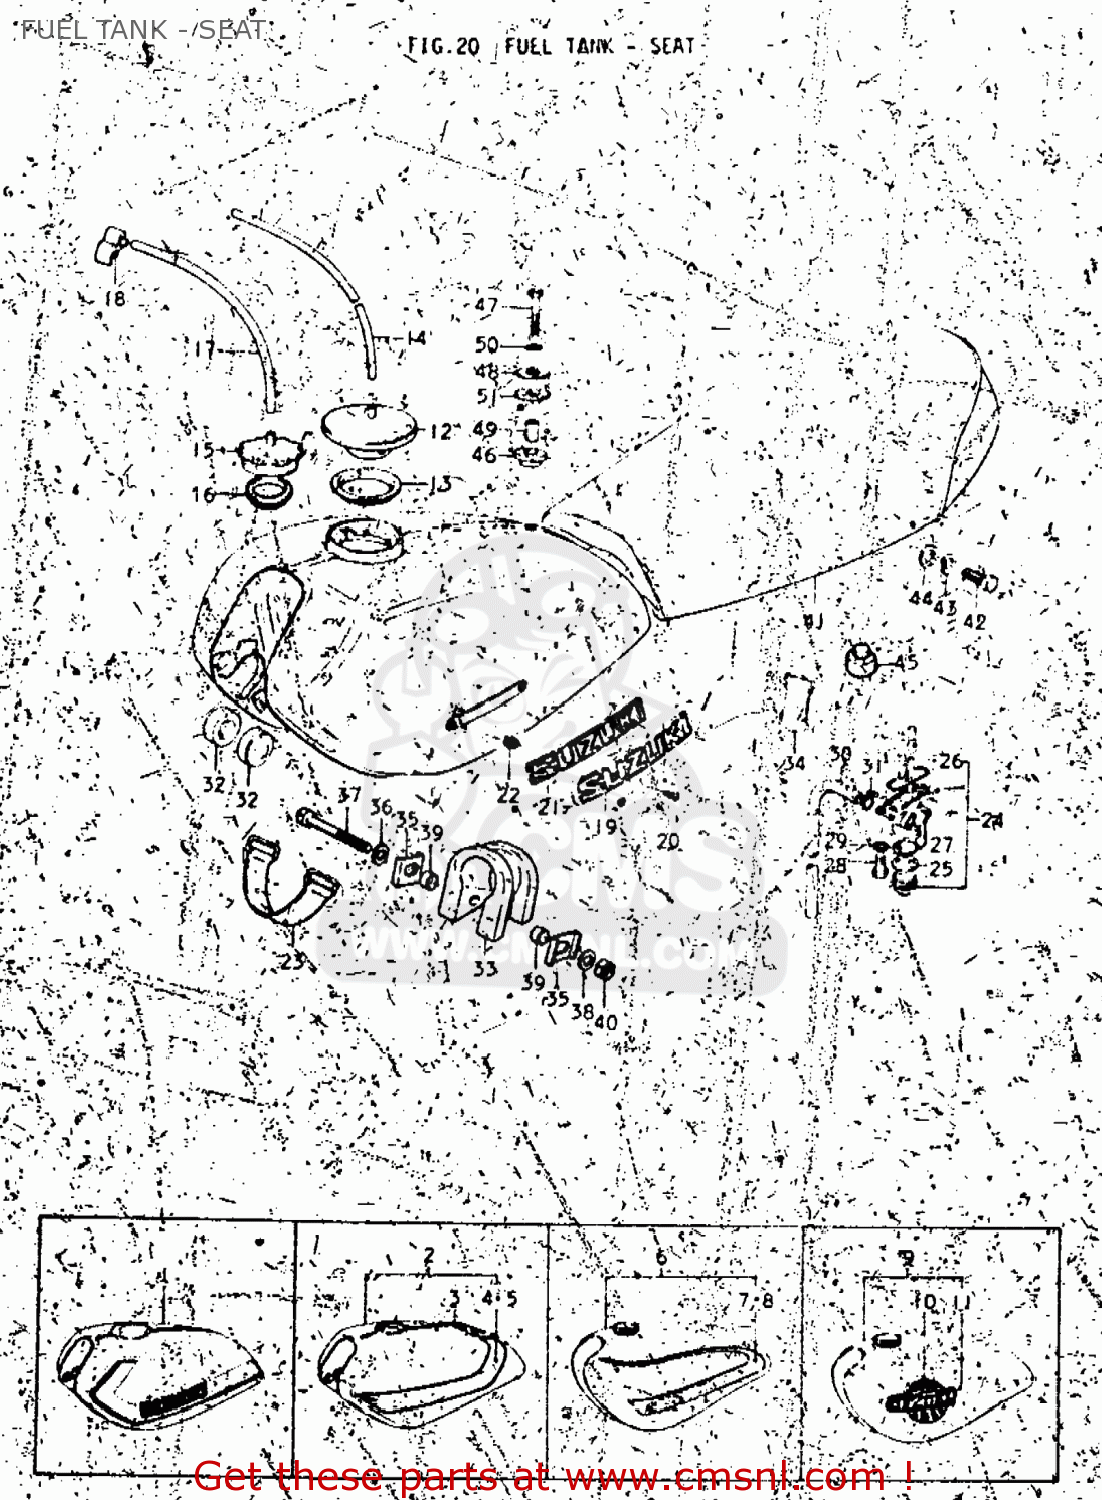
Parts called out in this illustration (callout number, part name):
1	TANK ASSEMBLY,FUEL
2	TANK ASSEMBLY,FUEL
4	TAPE,FUEL TANK
5	TAPE,FUEL TANK
6	TANK ASSEMBLY,FUEL
7	TAPE,FUEL TANK
8	TAPE,FUEL TANK
9	TANK ASSEMBLY,FUEL
10	TAPE,FUEL TANK
11	EMBLEM
12	CAP SET,FUEL TANK
13	GASKET,FUEL TANK CAP (NAS)
14	HOSE
15	CAP ASSY,FUEL TANK FILLER
16	GASKET,FUEL TANK CAP (NAS)
17	HOSE
18	CLAMP,FUEL
19	EMBLEM
20	SCREW
21	EMBLEM
22	NUT
23	BAND
24	COCK ASSEMBLY,FUEL
25	GASKET,FILTER (NAS)
26	COCK ASSEMBLY,FUEL
27	NET,STRAINER
28	SCREW
29	GASKET
30	HOSE
31	CLIP
32	CUSHION
33	CUSHION,FUEL TANK,REAR
34	BAND
35	CLIP
36	CUSHION
37	BOLT
38	WASHER 6MM
39	SPACER (6.1X8X5.2)
40	NUT
41	SEAT ASSEMBLY
42	BOLT
43	LOCK WASHER
44	WASHER
45	CUSHION
46	CUSHION
47	** SUPERSEEDED
48	WASHER
49	SPACER
50	LOCK WASHER
51	CUSHION
